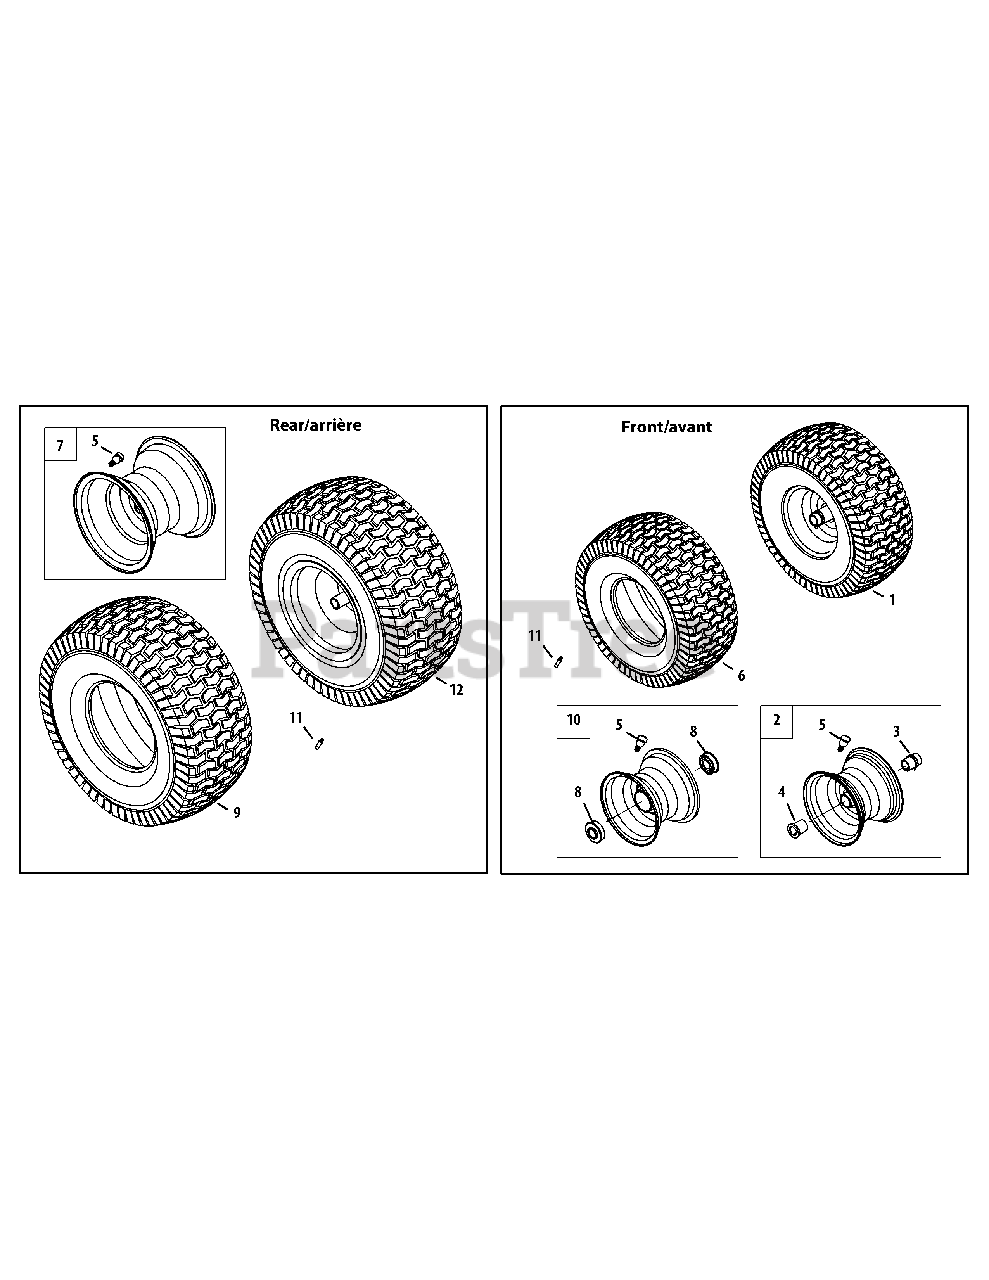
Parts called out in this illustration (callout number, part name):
1	Wheel Ass’y, 16 x 6.5 Ball Brg. (Grey)
2	Rim Ass’y, Plst. Brg.
3	Flg. Bearing .760 ID w/fitting
4	Flg. Bearing .760 x 1.0 x 1.20
5	Air Valve
7	Rim Ass’y, 12.0 x 7.0 (Grey)
8	Ball Bearing .750 ID x 1.750 OD
9	Tire, 22 x 9.5 x 12 Square Shoulder
9	Tire, 23 x 10.5 x 12 Square Shoulder
10	Rim Ass’y, Ball Brg. (Grey)
11	Grease Fitting
12	Wheel Ass’y, 23 x 10.5 x 12 (Grey)
